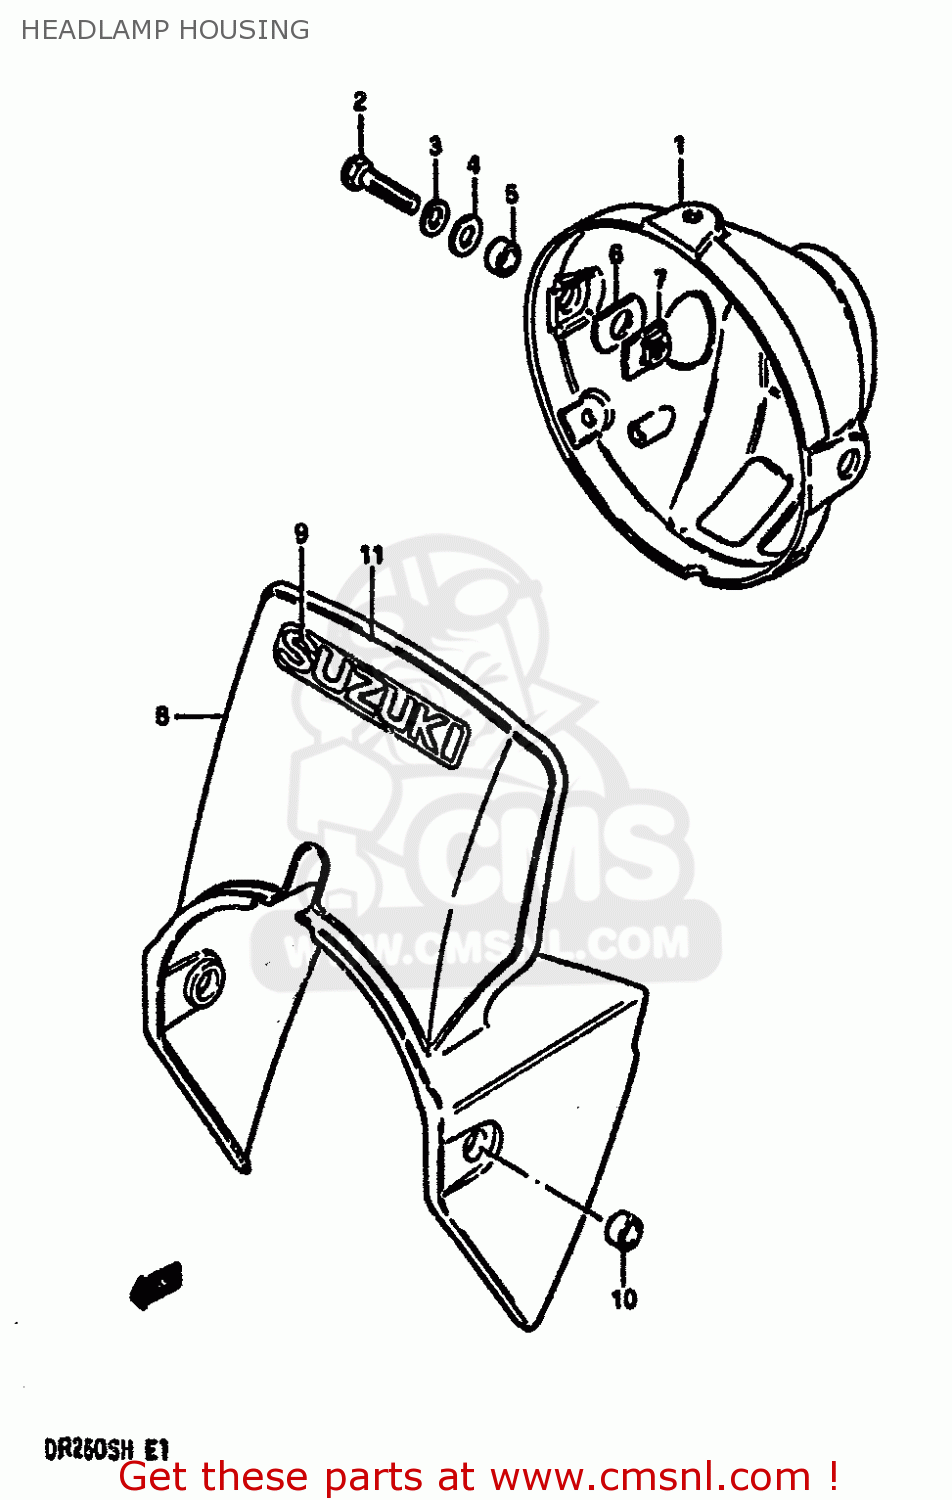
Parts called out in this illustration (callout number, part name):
1	HOUSING,HEAD LAMP
2	BOLT
3	LOCK WASHER
4	WASHER
5	SPACER (8.8X12X7)
6	CUSHION
7	PLATE,HEADLAMP HOUSING
8	COVER,HEADLAMP (BLUE)
9	EMBLEM
10	SPACER
11	TAPE SET,HEAD LAMP COVER
